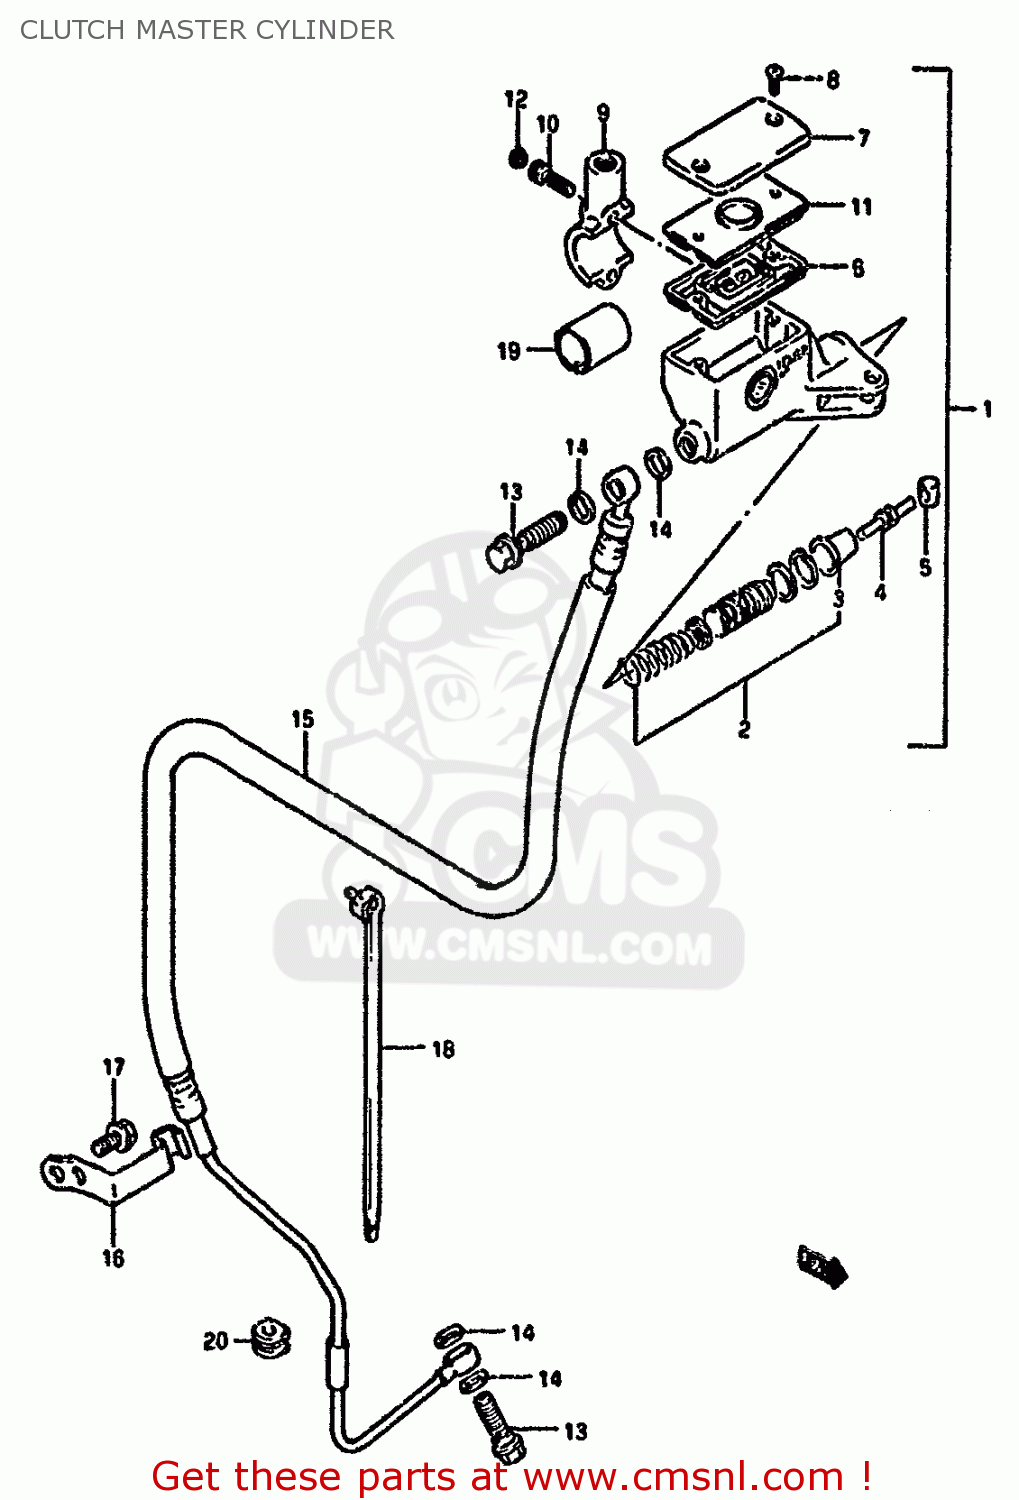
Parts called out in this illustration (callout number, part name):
1	CYLINDER ASSEMBLY,CLUTCH MASTER
2	PISTON & CUP SET
3	BOOT
4	PUSH ROD
5	BUSH
6	7
7	CAP
8	SCREW,RESERVOIR CAP
9	HOLDER
10	BOLT
11	PLATE,DIAPHRAGM
12	CAP(OD:10)
13	BOLT UNION
14	WASHER(10X15X1.5)
15	HOSE COMP,CLUTCH
16	GUIDE,CLUTCH HOSE
17	BOLT
18	CLAMP
19	SPACER,CLUTCH MASTER
20	GROMMET,CLUTCH HOSE
